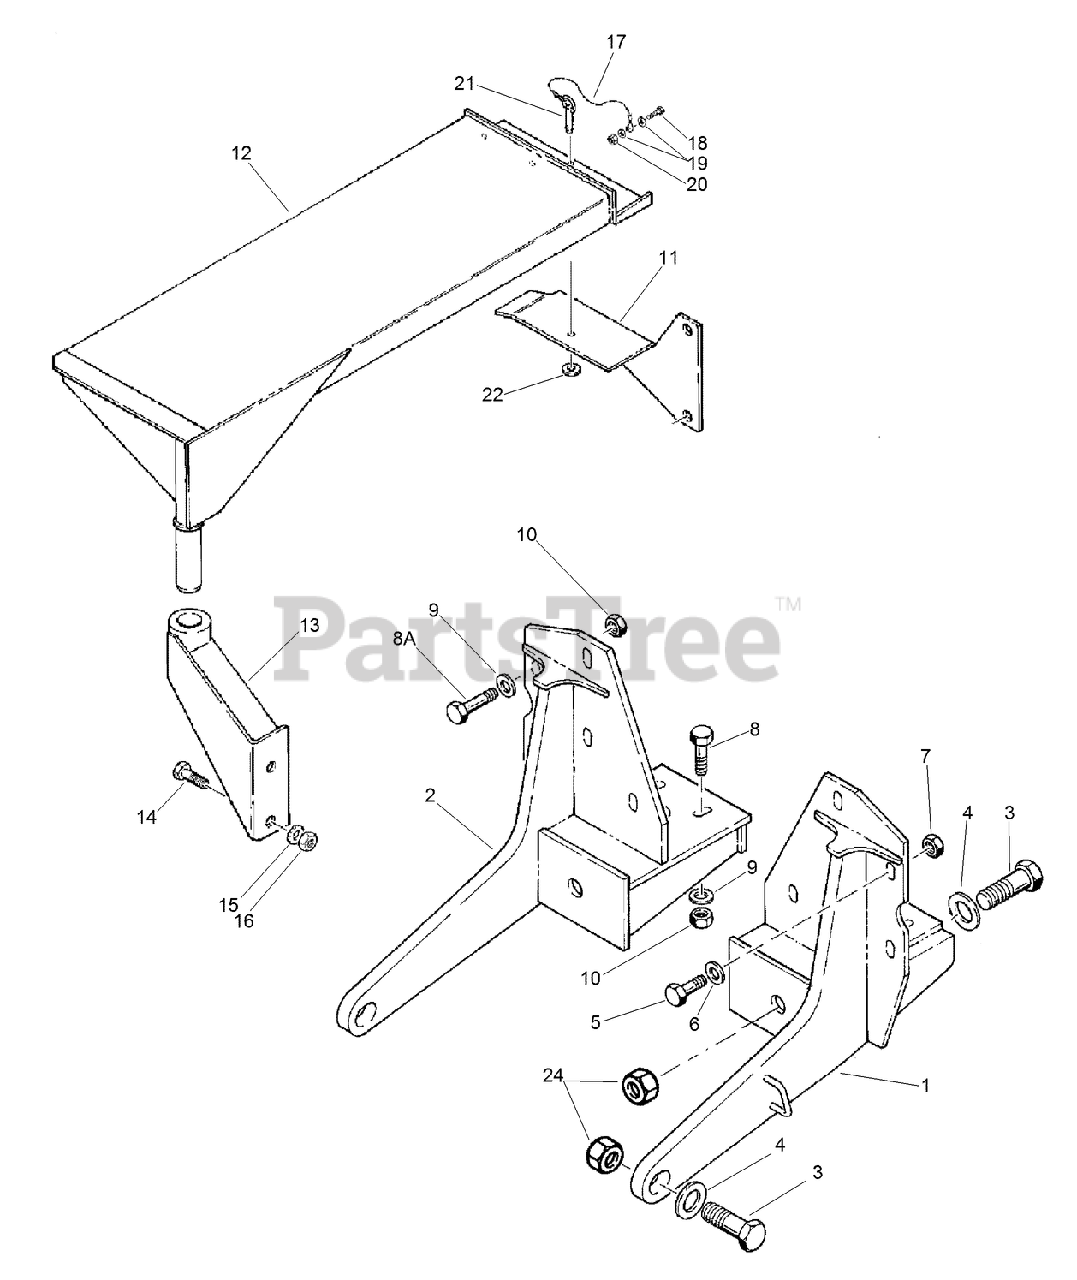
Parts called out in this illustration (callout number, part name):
1	BRACKET-Backhoe Mounting RH
2	BRACKET-Backhoe Mounting LH
6	WASHER-Flat
7	NUT-Prev Trq 3/4 GRC CAD Direct
8A	SCREW-HH
9	WASHER-Flat
10	NUT-Prev Trq 3/4 GRC CAD Direct
11	BRACKET-Walkway Support
12	WALKWAY-backhoe
13	PIVOT-Walkway Mounting
14	BOLT-Hex Hd 3/4 x 1-3/4 GR8 ZND
15	WASHER-Flat
16	NUT-Prev Trq 3/4 GRC CAD Direct
17	RETAINER-ROPE, WIRE
18	SCREW-HH
19	WASHER-FLAT
20	NUT-HEX
21	PIN-Cotterless
22	WASHER-0.406 x 0.812 x 0.065 in CST ZND
24	NUT-hex, self-locking, 1-1/4 inch NC
